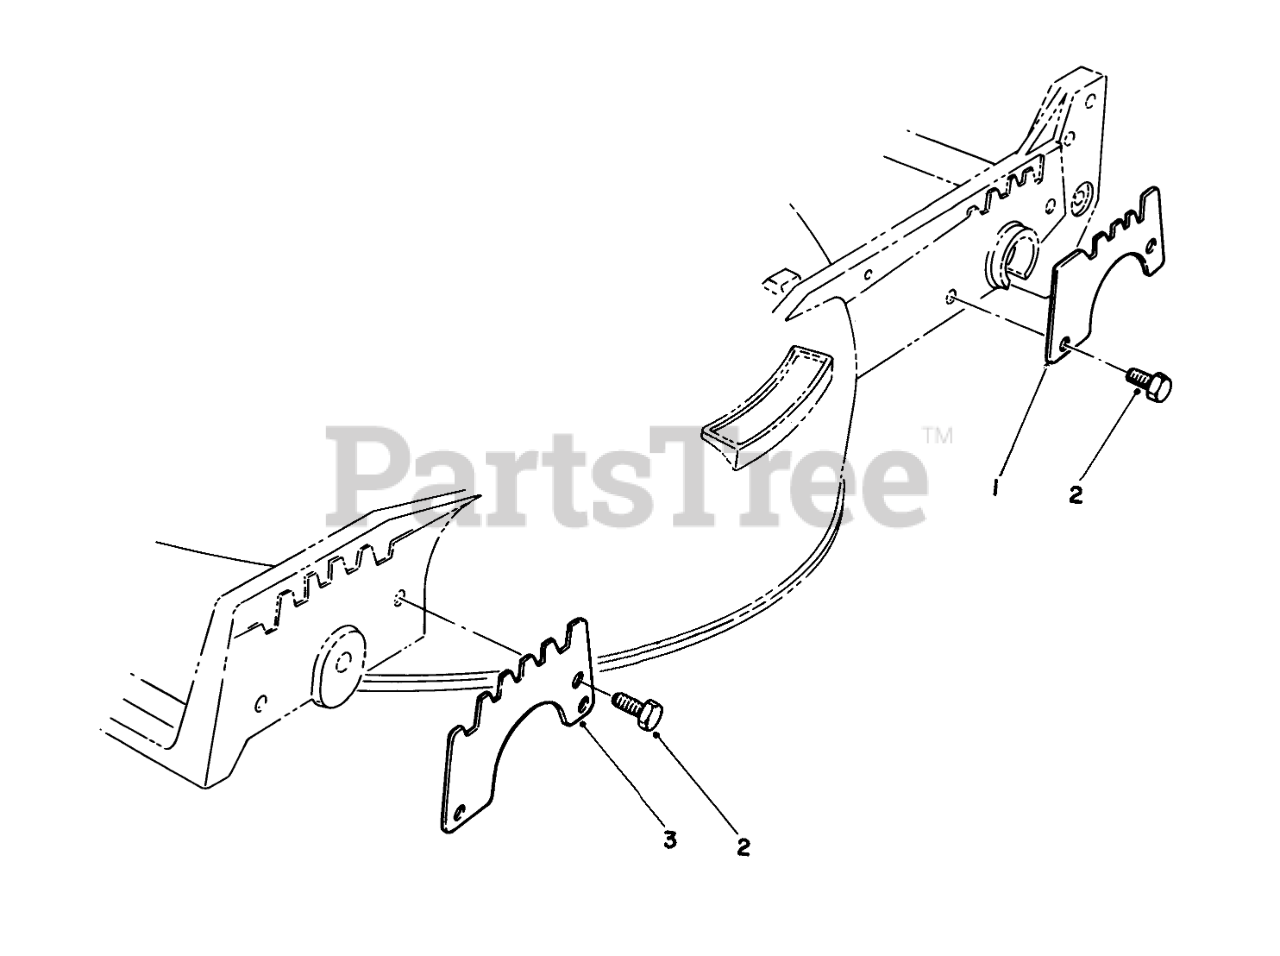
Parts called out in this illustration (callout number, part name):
1	WEAR PLATE,REAR
2	SCREW-HWH
3	WEAR PLATE
